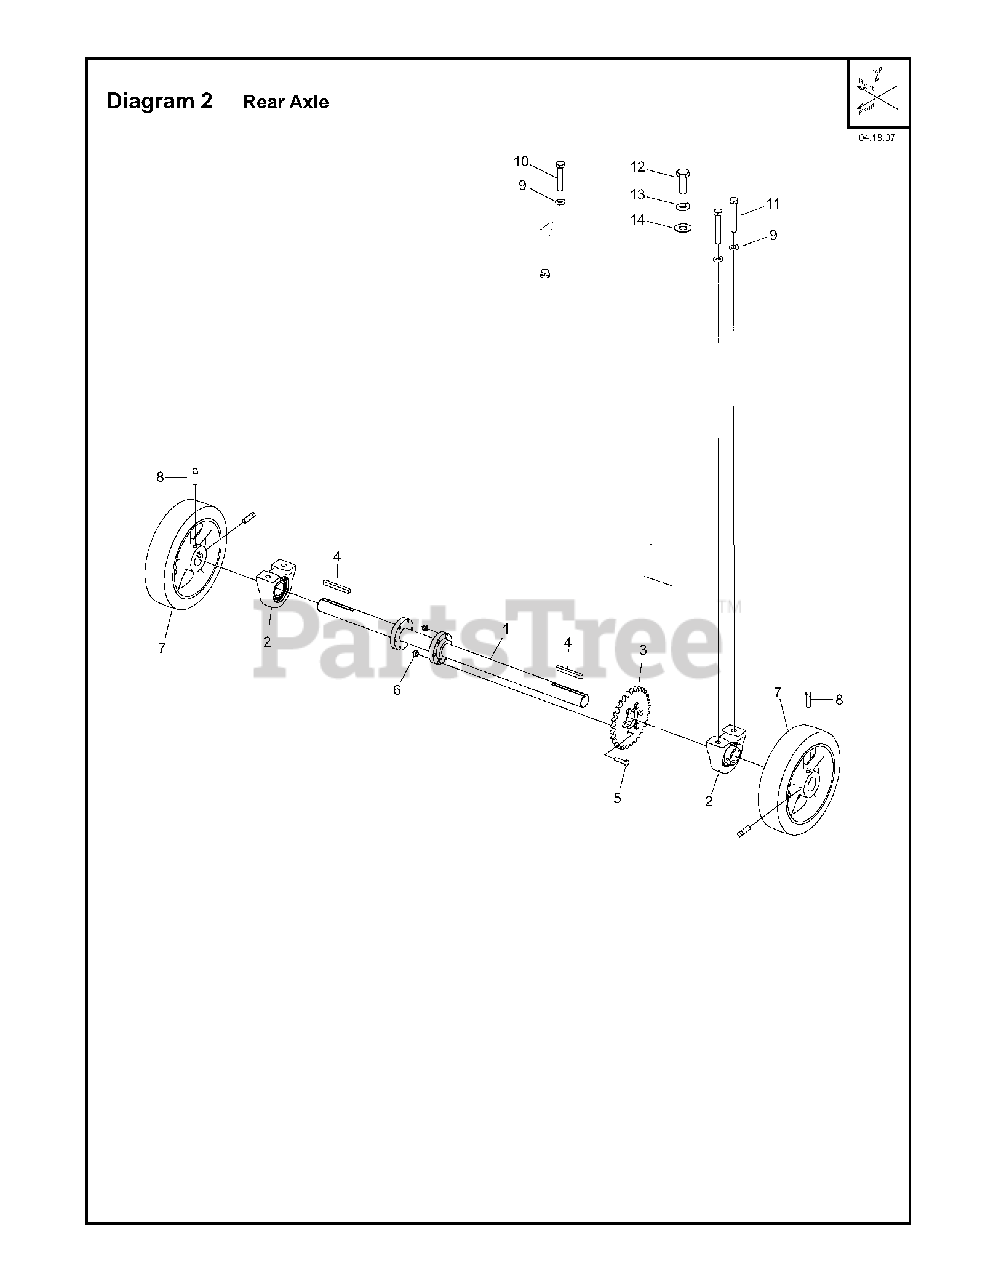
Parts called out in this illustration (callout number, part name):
2	BRG 1 PILLOWBLOCK BB
4	KEY. .25 SQ X 2.25
5	HHCS. M6 x 1.0 x 25 DIN931 Z/P
6	LOCKNUT. FIBER M6 DIN 985
8	SQHSS. .3125-18 x 1 Z/P
9	LOCKWASHER. SPLIT .375
10	HHCS. .375-16 x 2.25 GR 5 Z/P
11	HHCS. .375-16 x 2.5 GR 5 Z/P
13	LOCKWASHER. SPLIT M12 DIN 127
14	WASHER
